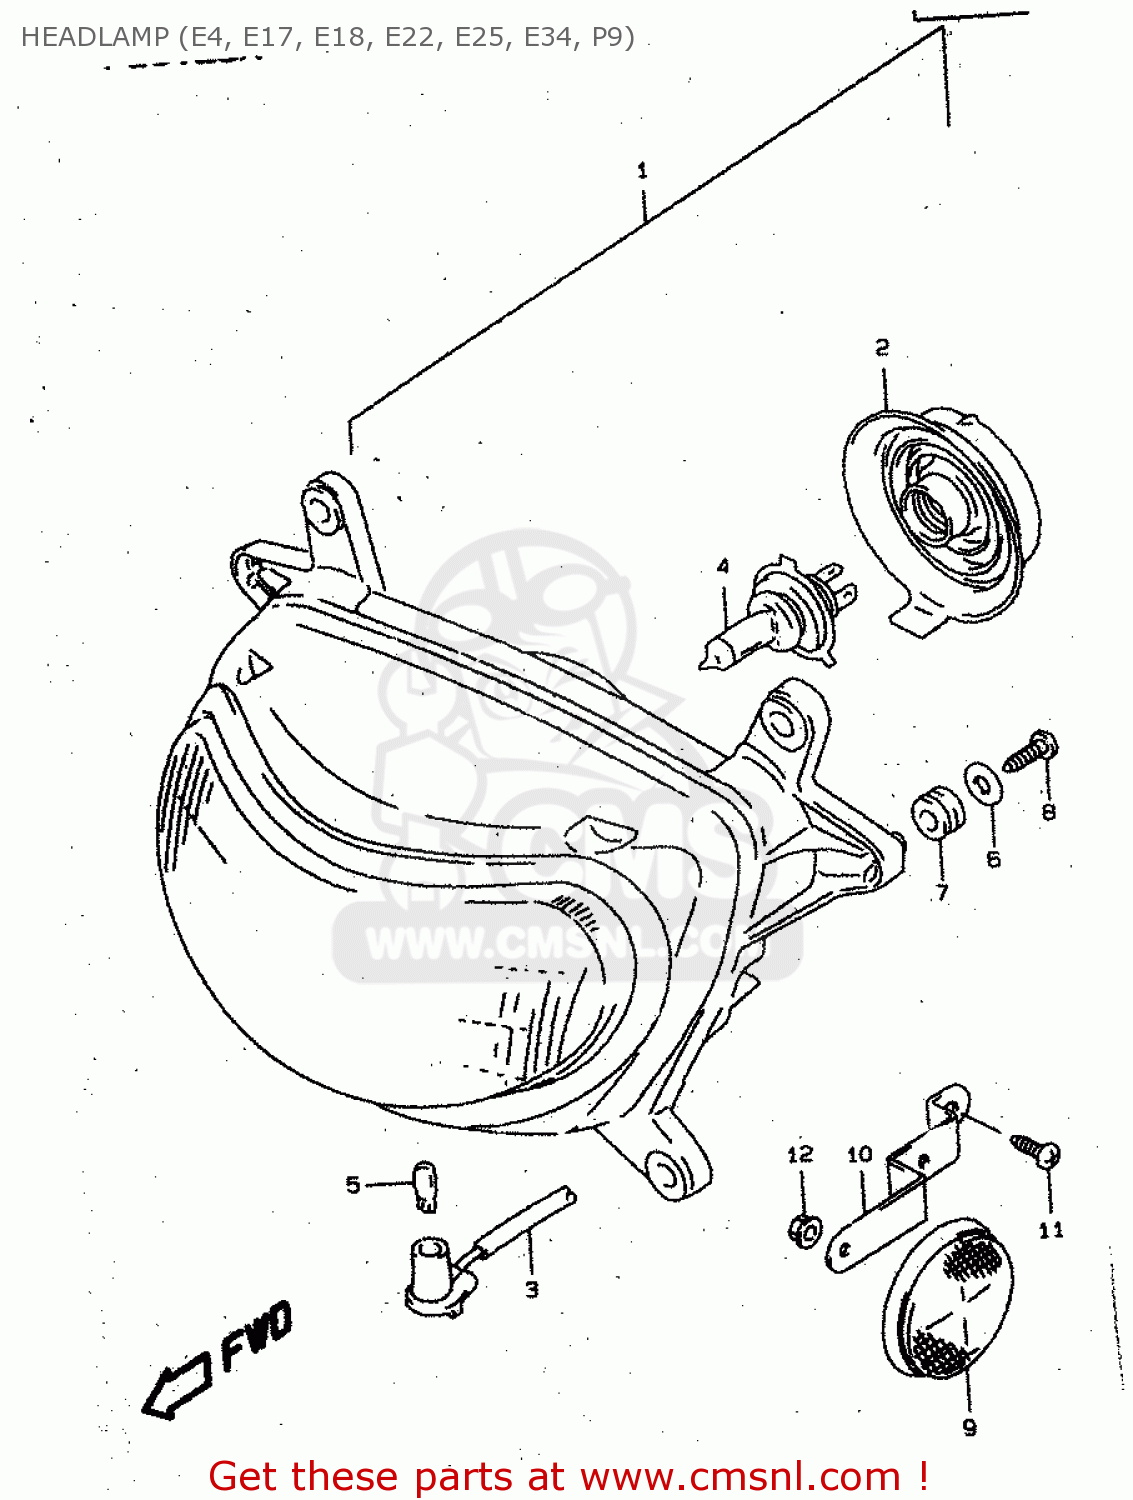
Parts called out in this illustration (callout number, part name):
1	HEADLAMP ASSY
2	COVER
3	CORD ASSY
4	BULB(12V60/55W,H4)
5	BULB(12V5W)
6	WASHER(5.5X18X1)
7	CUSHION
8	SCREW
9	REFLECTOR,REFLEX
10	BRACKET,FR SIDE RR
11	SCREW,SIDE HOL
12	NUT
